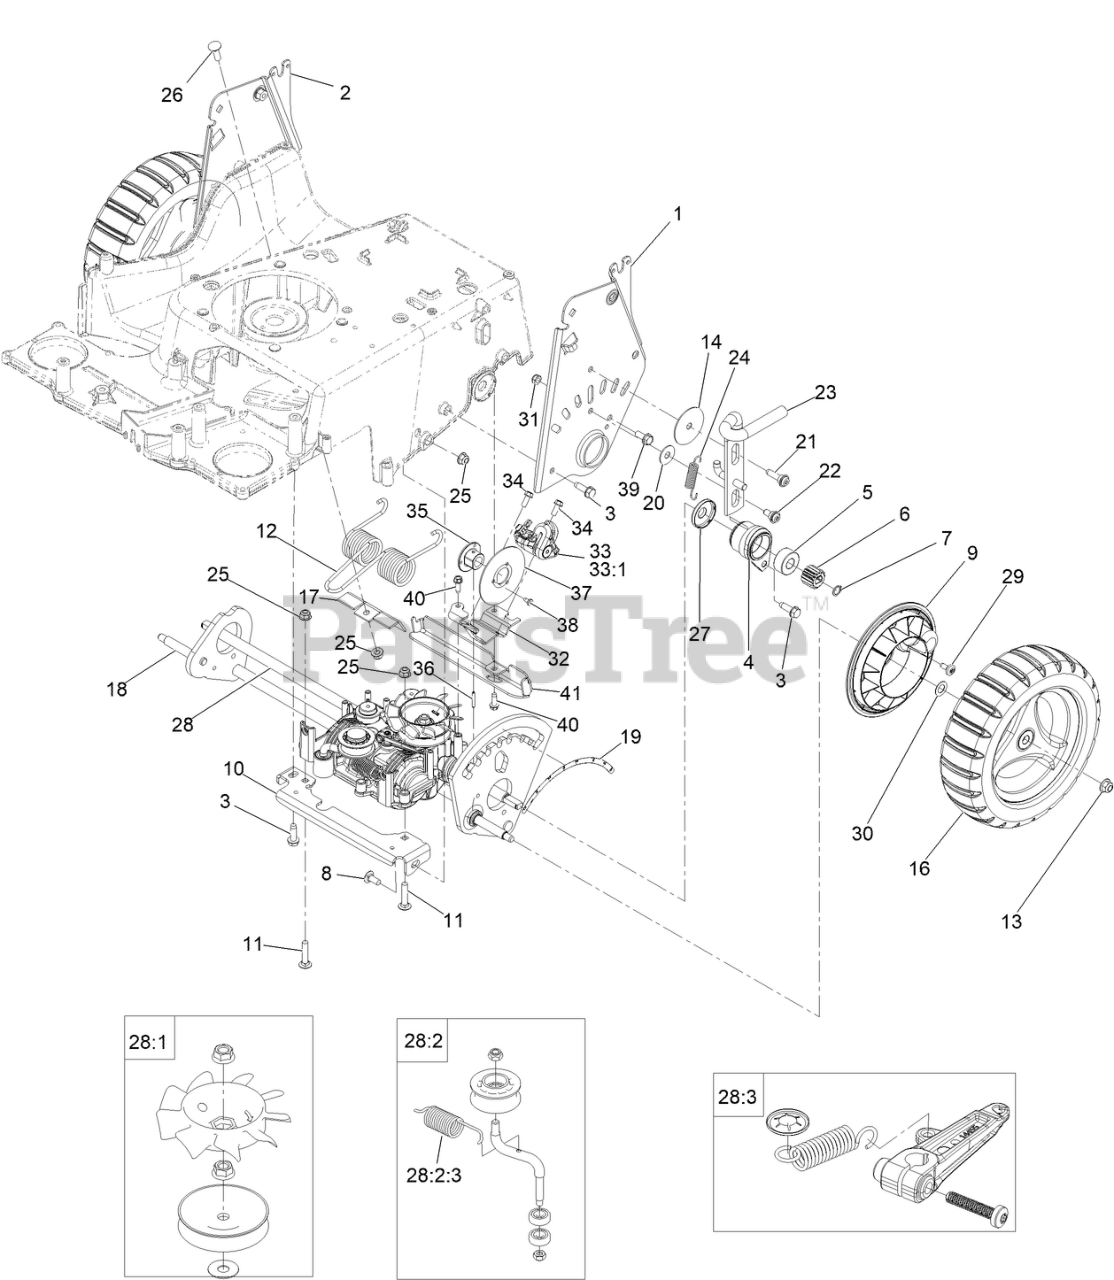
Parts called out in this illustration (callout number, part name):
1	HOC Plate Assembly
2	HOC Plate Assembly
3	SCREW-THD ROLL, HWH
4	Bearing Retainer ASM
5	BEARING-BALL, CUSTOM
6	GEAR-PINION, 15T
7	RING-RETAINING
8	SCREW-CARR
9	Cover-Wheel
10	Bracket-Transmission, Front
11	BOLT-CARR
12	SPRING-TORSION
13	NUT-HF, NI
14	WASHER-PLAIN
16	WHEEL ASM, 10.5 W/GEAR
17	BRACKET
18	REAR AXLE ASM
19	DECAL-HOC, REAR
21	SCREW-SHOULDER, BHTF
22	BOLT-SHOULDER
23	LOCK-HEIGHT, ADJ
24	Wheel ASM, 10.5 W/Gear
25	NUT-HF, NI
26	BOLT-CARR
27	COVER-BEARING
28	TRANSMISSION-MV702
28:1	Pulley & Fan Repair Kit
28:2	Idler Pulley Repair Kit
28:2:3	Spring-Tension, Belt
28:3	Clutch Lever Repair Kit
29	SCREW-SHOULDER
30	WASHER-PLAIN
31	NUT-LOCK, NI
32	Bracket-Mount, Brake
33	CALIPER-BRAKE, DISC
34	SCREW-HWH
35	Hub-Rotor
36	Pin-Roll
37	Disc-Rotor
38	SCREW-TORX PH THD ROLL
40	SCREW-HWHTF
41	Bracket-Support, Cable
